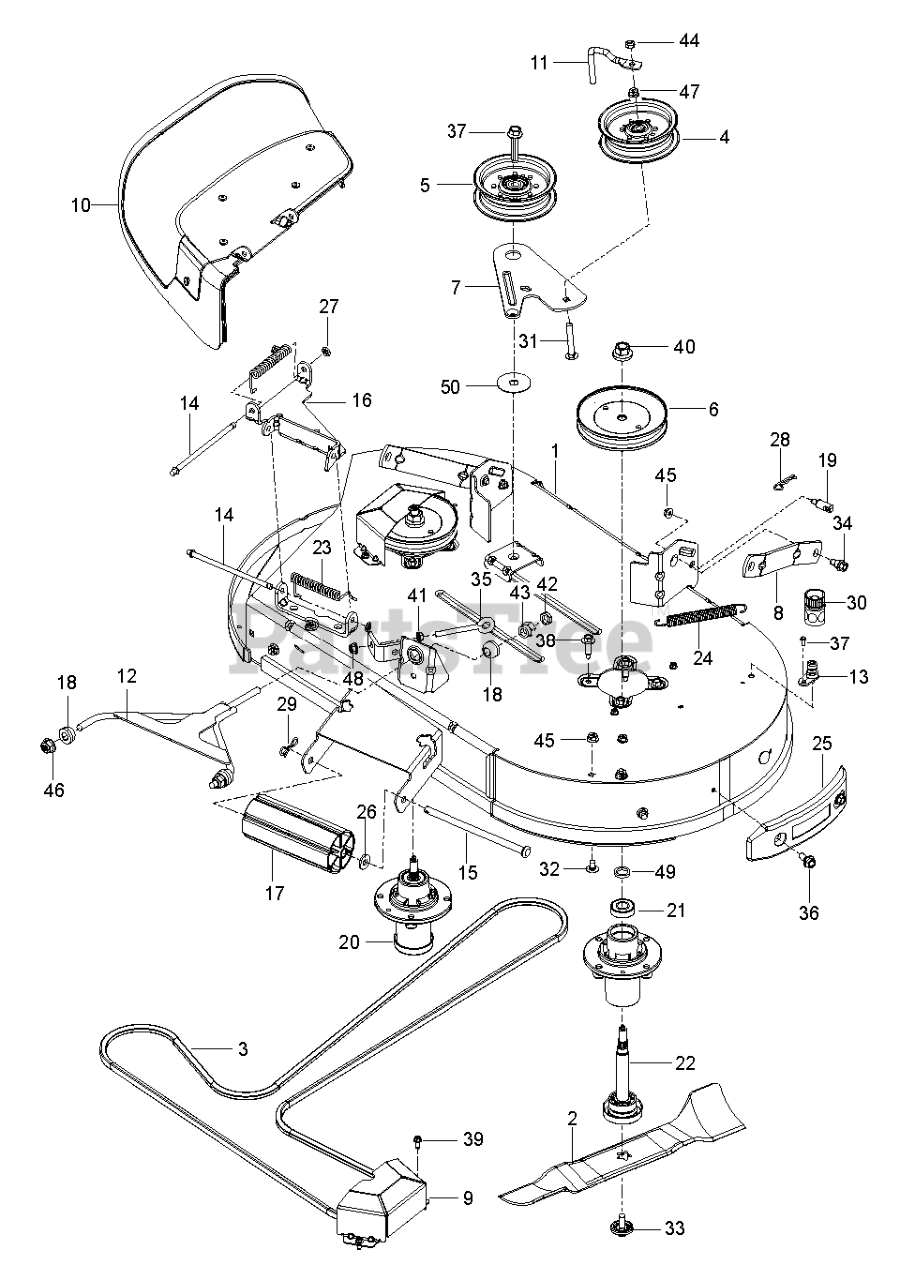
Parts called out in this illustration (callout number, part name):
1	HOUSING.PNT.WLD.CLRCT42.ZTR.OR
2	BLADE.42.FCS.BAGGING.BLADE.RAW
3	BELT.42.FCS.ZTR.DECK.DRIVE
4	PULLEY.IDLER.2006
5	PULLEY.IDLER.MWR.STATI.LH
6	PULLEY MANDREL 5.0"
7	ARM.42"FCS.CLUTCHING.X431
8	ARM.RFIXED.MOWER.SUSPNSIONX431
9	COVER.42".MANDREL.FCS.PNT.498
10	DEFLECTOR.ASM.42.FCS.ORANGE
11	KEEPER.BELT.IDLER.54"T
12	LINK.RZ.FRONT.WELDMENT.E-DIP
13	PORT.WASHOUT
14	ROD.HINGE
15	ROD.ROLLER.NOSE.NARROW.48"
16	BRACKET.42".FCS.DBLE.HINGEX668
17	NOSE ROLLER 48"
18	BUSHING SPHERICAL SUSP. FRONT
19	STUD.FASTNER.W/ANTI-ROTATE
20	MANDREL ASM, CAST IRON
22	SHAFT ASM MANDREL
23	SPRING.42.FCS.DEFLECTOR
24	SPRING.MOWER.DRIVE.ELECTRIC
25	BUMPER.42.CLEARCUT.TRIMSDE.ASM
26	BUSHING.NOSE.ROLLER
27	NUT PUSH M
28	HAIRPIN #4
29	PIN.COTTER.5/16.BOW TI
30	COUPLING.QUICK CONNECT
31	CARRIAGE BOLT 3/8-16 X
32	CARRIAGE BOLT 5/16C X 5/8"
33	BOLT.WASHER.ASM.7/16-2
34	BOLT.SHOULDER
35	EYE BOLT 5/16 X 3.50
36	SHOULDER BOLT 5/16-18TT
37	SCREW.7/16-14 X 2.125.WASHER
38	BOLT.HEX.WASHR.HED.313-18X1.19
39	SCREW.1/4-20X5/8
40	NUT.FLANGE.LOCK.TOP
41	NUT 5/16C WHIZ
42	NUT **
43	NUT, LIFT LINK 7/16-20
44	NUT LOCK FLG 3/8-16 UNC
45	NUT LOCK HEX FLANGE 5/16-18
46	7/16-14 HEX NUT W/NYL RING ZD
48	5/16-18 NYLOC FLANGE NUT
49	WASHER.SPACER.MANDREL
